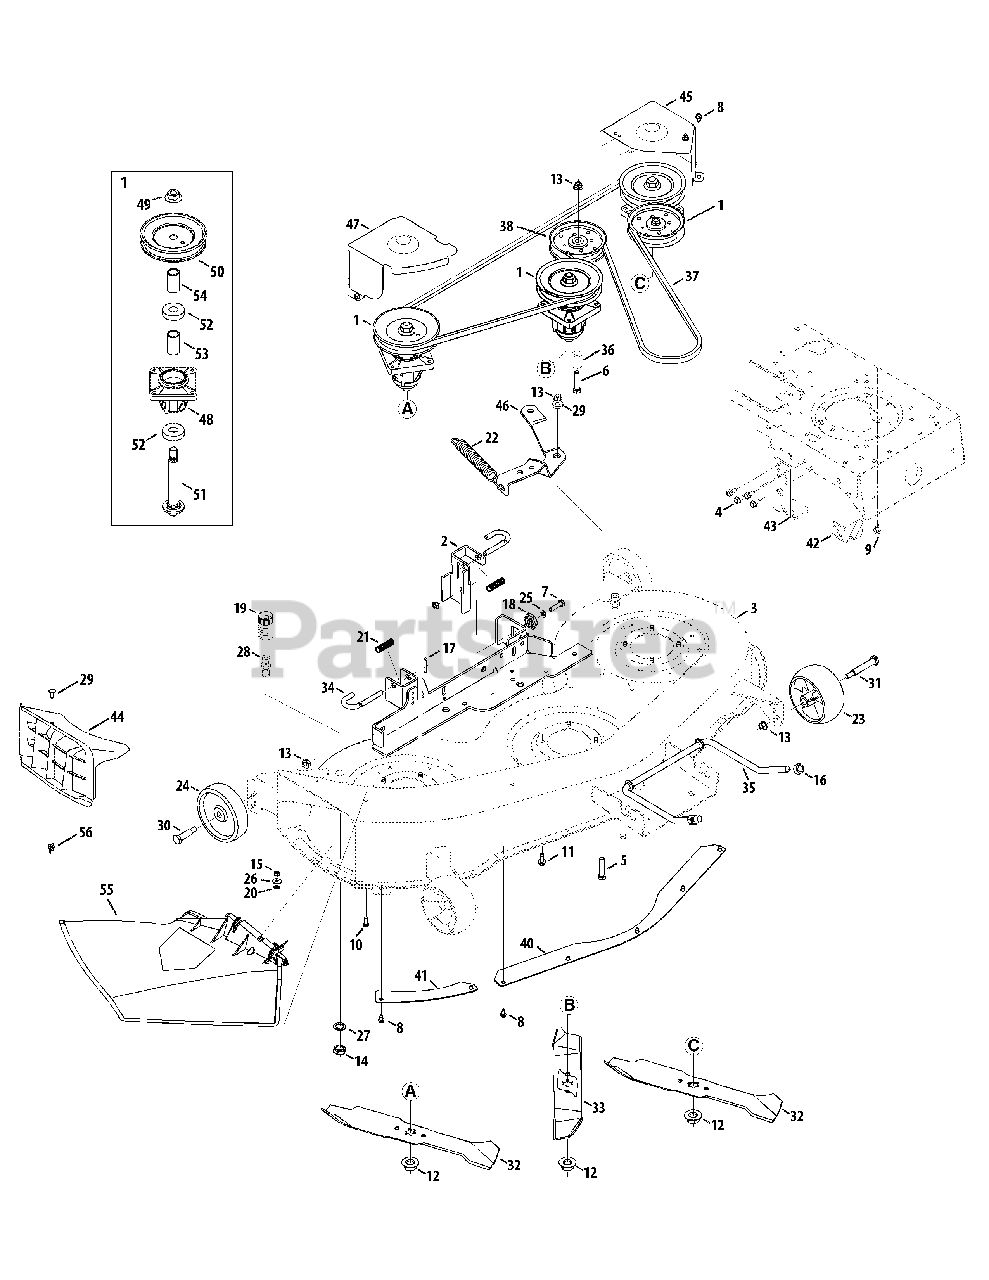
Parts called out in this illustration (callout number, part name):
1	Spindle Assembly
2	Deck Hanger Bracket Ass'y
3	Deck Assembly
4	Hex Wash Hd. Tapp Scr. 5/16-18 x .75
5	Hex Screw 3/16 x 1.00
6	Hex. Hd. Cap Scr. 3/8-16 X 3.0 Gr. 8
7	Hex Bolt 5/16-18 x 1.25
8	Hex Wash S-Tapp Scr 1/4-20 x .50
9	Hex Wash HD S-Tapp Scr 5/16-18 x .50
10	Hex. Hd. Cap Scr. 3/8-16 X 3.0 Gr. 8
11	Hex Wash. Hd. Scr. 5/16-18 x .75 Lg.
12	Hex Flange Nut 5/8-18
13	Hex. Flanged L-Nut 3/8-16 Gr. F
14	Hex Nut M16-1.5 DIN 936
15	Hex Nut 1/4-20 Gr. 5
16	Hex Nut, 1/2-13
17	Cotter Pin 3/32 x 1.0
18	Deck Adjustment Gear
19	Water Nozzle Adapter
20	Pushnut 1/4 x .50
21	Compression Spring .531 OD x 1.75 Lg
22	Extension Spring
24	Wheel Ass’y - Deck 5" x 1.38"
25	L-Wash 5/16 ID
26	Cupped Washer .265 ID x .75 OD x .062
27	Lockwasher Schnorr 17 x 23.8 x 1.95
29	Shoulder Spacer 1.0 x .38 X .38
30	Shoulder Bolt .498 Dia x 1.53 x 3/8-16
31	Shoulder Bolt 3/8-16 x .496 x 2.5
32	Three-in-one Blade, Star Centre 16.28"
33	Three-in-one Blade, Star Centre 14.88"
34	Deck Release Pin
35	Front Adjustment Deck Rod
36	Spacer 3/8 ID x 1.0 x 1.25
37	V-Belt Type A 118.20" Lg.
38	Idler Pulley 4.06 Dia
40	Center Deck Skirt
43	Deck Stop Bracket
44	Mulching Plug
47	Belt Cover RH
48	Spindle Housing
49	Hex Flange Nut 5/8-18
50	Deck Pulley 5.75 Diam.
51	Spindle Shaft
52	Ball Bearing 20 x 47 x 14:6204:DS
53	Spacer .792 x 1.060 x 1.860
54	Spacer .807 x 1.0 x 3.03
55	Chute Ass'y
56	Wing Nut 1/4-20 Thd.
